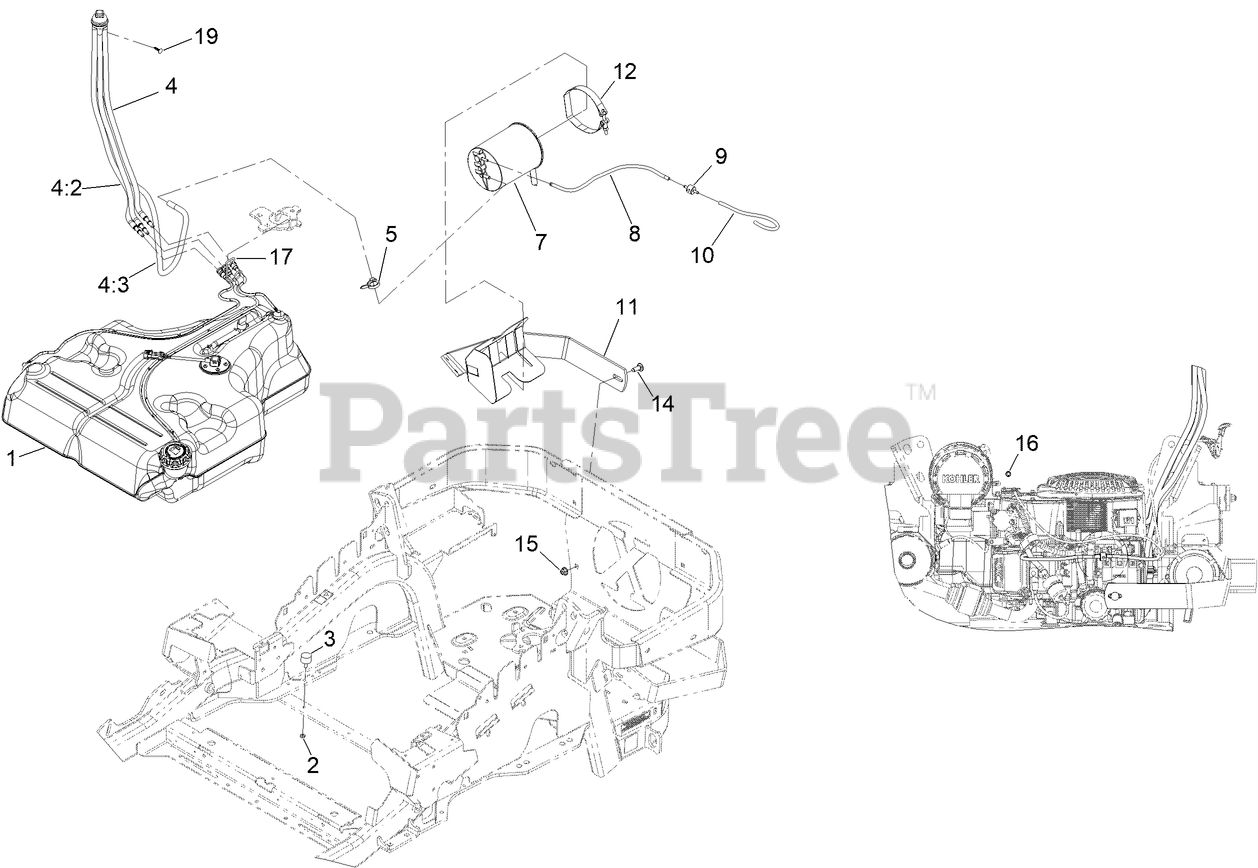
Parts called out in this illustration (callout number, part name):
1	FUEL TANK ASM
2	NUT-JAM
3	BUMPER
4	FUEL MANIFOLD VENT ASM
4:2	HOSE-FUEL
4:3	HOSE-FUEL
5	CLAMP-HOSE
7	CANISTER-CARBON, 1200CC
8	HOSE-VENT, FORMED
9	VALVE-CHECK, VACUUM
10	HOSE-VENT, FORMED
11	MOUNT-CANISTER
12	CLAMP, T-BOLT
14	SCREW-CARR
15	NUT-HF, NI
16	PLUG-PORT
17	RETAINER-LINE, VAPOR
19	PLUG-PLASTIC
